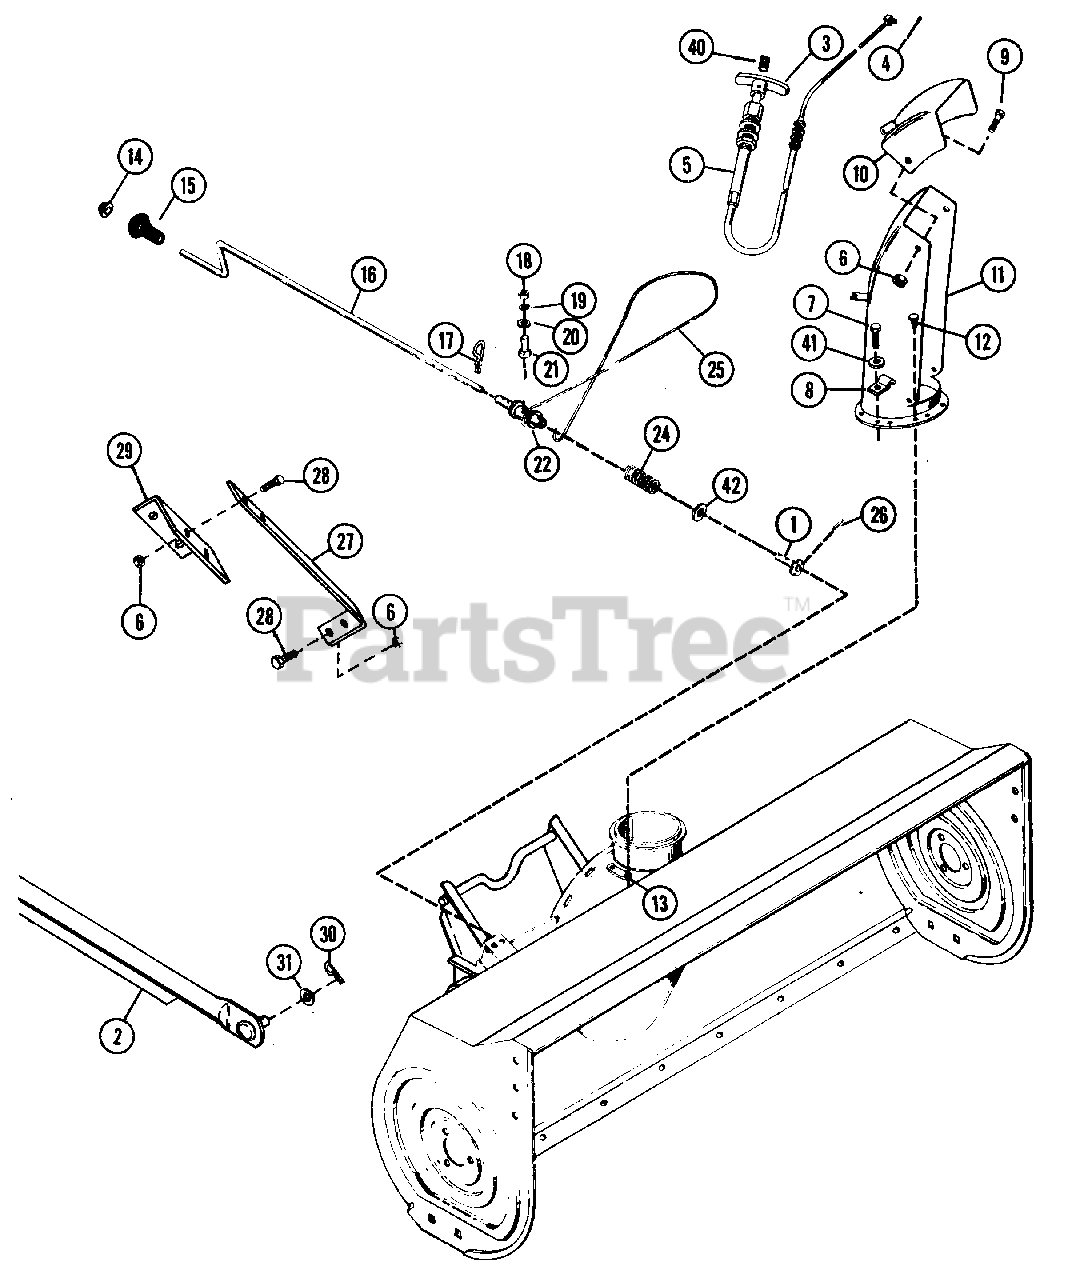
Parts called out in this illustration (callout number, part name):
1	ARM, DISC
2	WELDMENT, PUSH ROD
3	HANDLE, TEE
4	PIN, COTTER .09X.75
5	CABLE, CONTROL
6	NUT, LOCK 3/8-16
7	SCREW, TAPTITE 10-24X.75
8	CLAMP, CABLE
9	BOLT, HEX 3/8-16X.75
10	DEFLECTOR, CHUTE
11	CHUTE, DISCHARGE
12	SCREW, TAPTITE 10-24X.375
13	CLAMP, CHUTE
14	CAP
15	KNOB
16	CRANK, CHUTE CONTROL
17	HAIR PIN, INTERNAL
18	NUT, HEX 1/4-20
19	WASHER, LOCK 5/16 REG.
20	WASHER, FLAT .281X.625X.065
21	BOLT, 1/4-20X.625 RD HD SQ NK
22	SPOOL
24	SPRING, COMPRESSION
25	CABLE
26	PIN, SPRING .187X1.000
27	BAR, CRANK BRACKET
28	BOLT, HEX 3/8-16X1.00
29	BRACKET, CRANK SUPPORT
30	COTTER, HAIR PIN
31	WASHER, FLAT .812X1.469X.134
40	SCREW, MACHINE 10-32X.50
41	WASHER, FLAT .219X.438X.049
42	WASHER, .635/.645X1.005X.062
NS	DECAL, GRAVELY LOGO
NS	DECAL, DANGER FOOT
NS	DECAL, DANGER HAND
NS	DECAL, AMERICA
NS	DECAL, CHUTE CRANK
